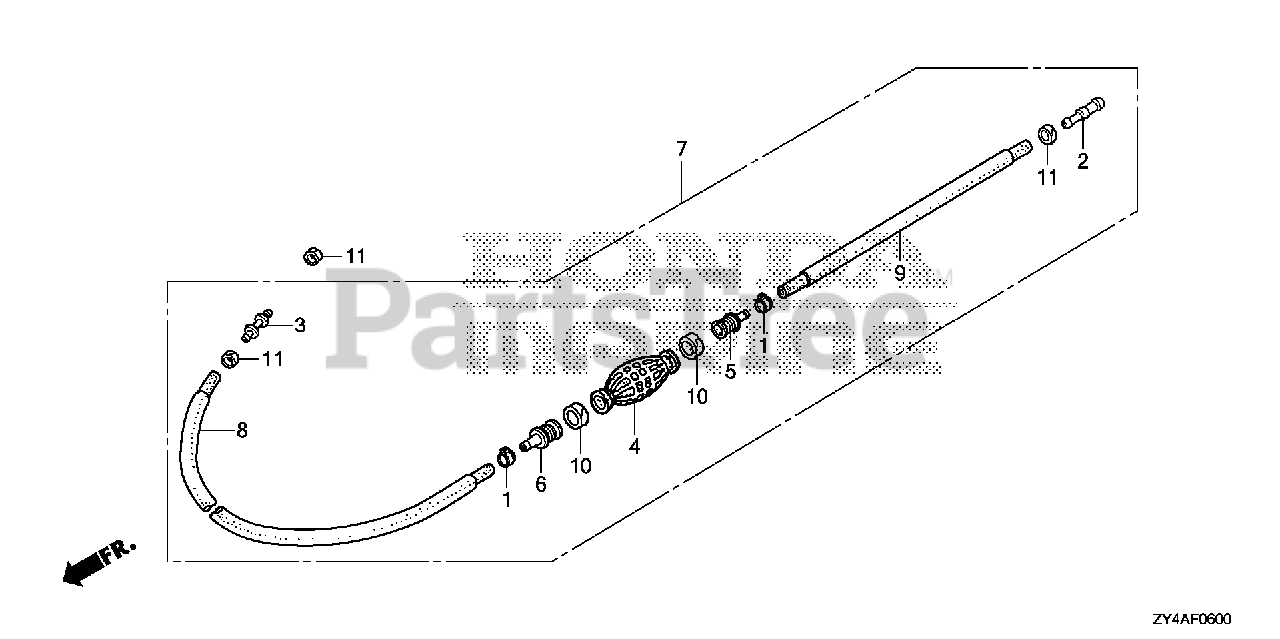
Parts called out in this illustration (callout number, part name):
1	CLAMP, FUEL TUBE (14.0)
2	JOINT, FUEL TUBE
3	JOINT, FUEL TUBE
4	BULB, PRIMER
5	VALVE, IN.
6	VALVE, OUTLET
7	TUBE ASSY., FUEL TANK (JOINT TYPE)(FKM)
7	TUBE ASSY., FUEL TANK
8	TUBE, FUEL LONG (7.3X2000)
9	TUBE, FUEL SHORT
10	BAND, TUBE CLIP (20MM)
11	BAND, TUBE CLIP (12.5MM)
